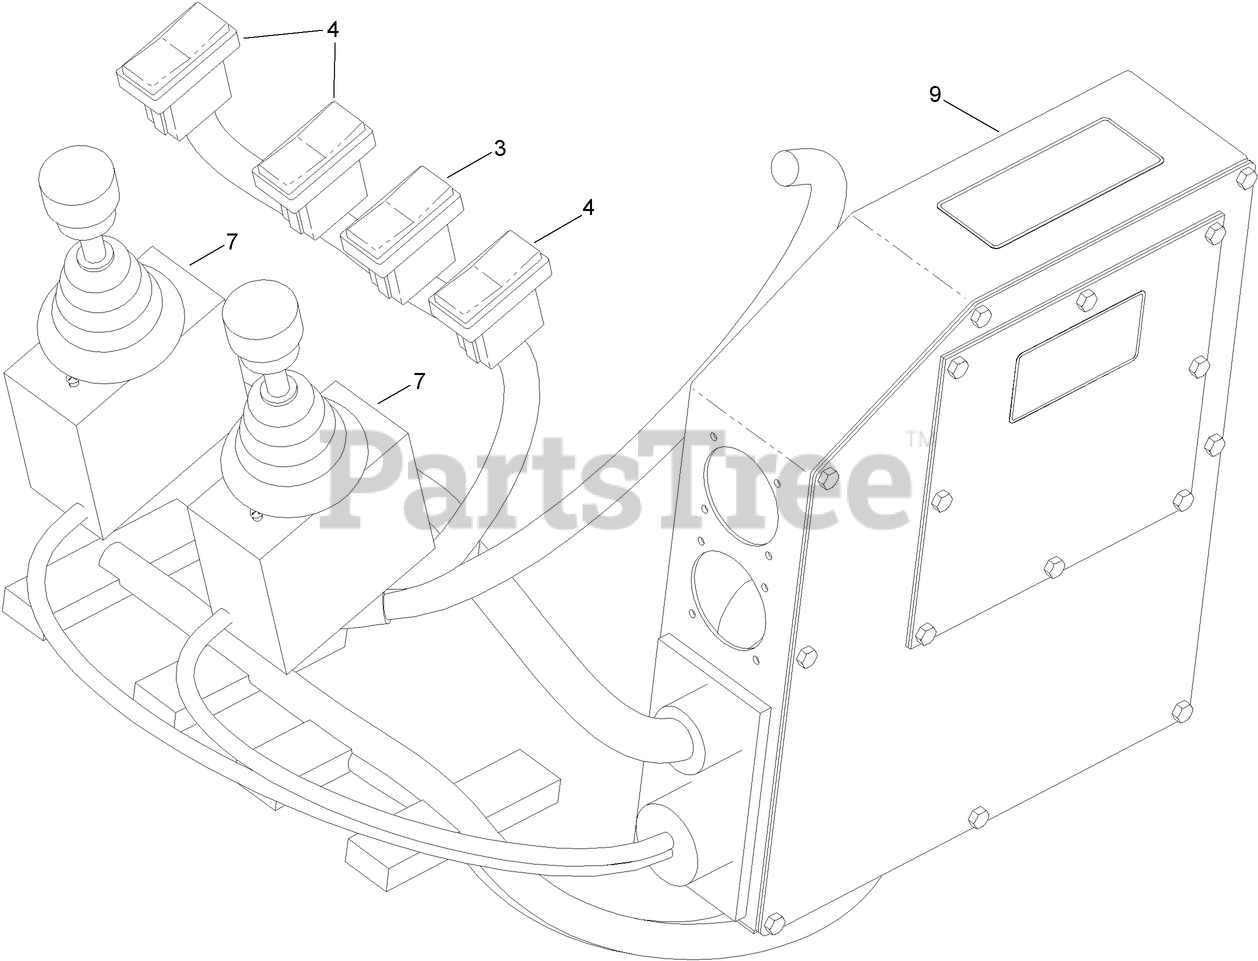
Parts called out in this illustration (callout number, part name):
3	SWITCH-ROCKER, 3 POSITION
4	SWITCH-ROCKER, 2 POSITION
7	CONTROLLER-JOYSTICK
9	BOX-JUNCTION, ELECTRIC
